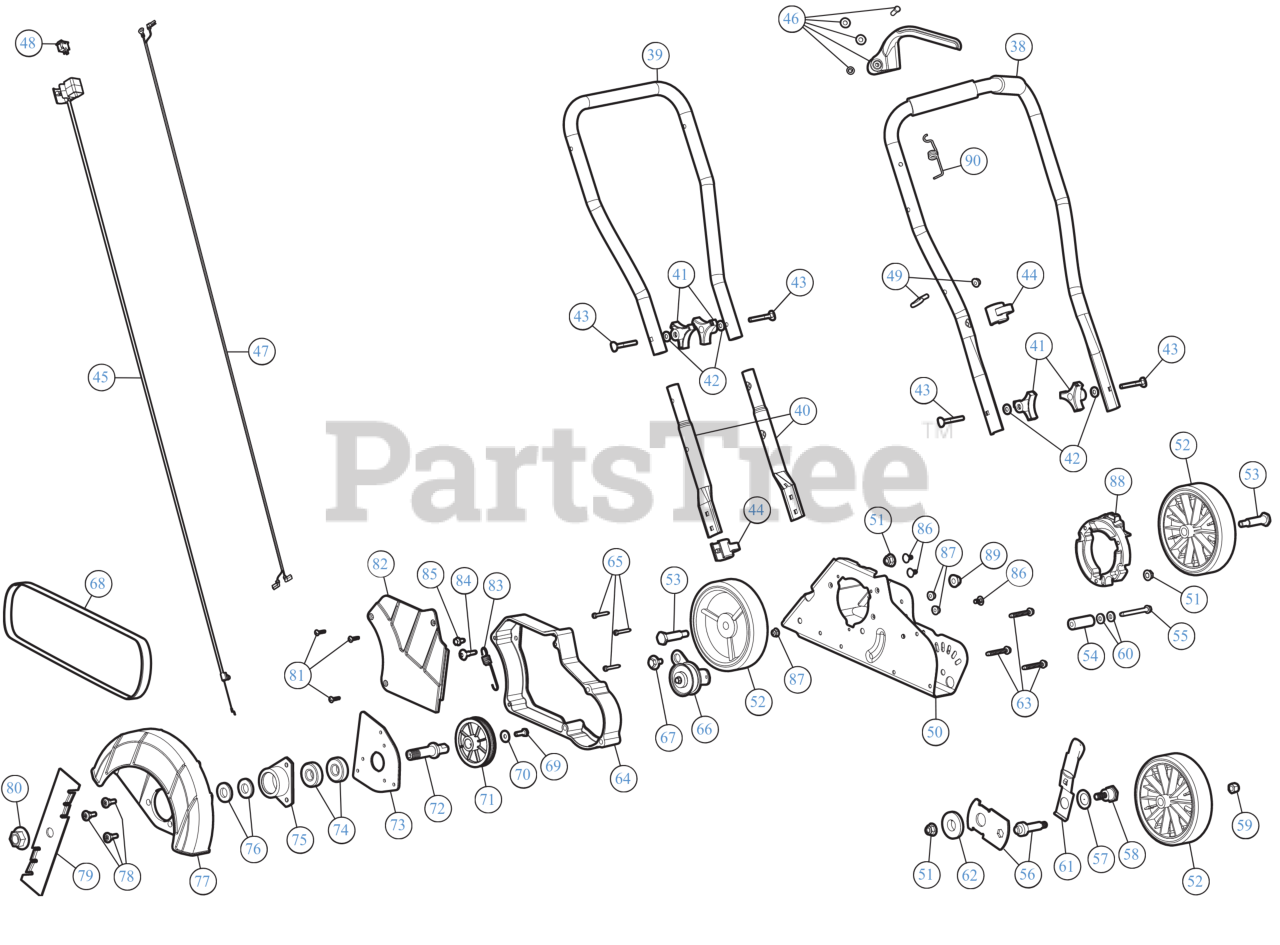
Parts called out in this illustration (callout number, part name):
38	HANDLE UP
39	HANDLE MID
40	HANDLE EXT
41	KNOB, 3-PRONG ¼ "-
42	WASH, FLAT SPECIAL
43	BOLT, CARRIAGE CRV
44	CABLE GUIDE
45	THROTTLE CABLE
46	THROTTLE LVR W/HDW
47	WIRE LEAD
48	SW, MOMENTARY ON/O
49	ROPE GUIDE
52	WHEEL 5-1.5 GRAY
53	SHOULDER SCREW
54	SPACER
55	SCREW 1/4-20 x 2.375
56	PIVOT ARM
57	BELL WASHER
58	SHOULDER SCREW .75 X.50 X3/8-16
59	HEX NUT INS L-3/8-16
60	SPACER
61	FRONT HEIGHT ADJUST LEVER ASSEMBLY
62	HEIGHT ADJUSTMENT BEARING
63	SCREW 1/4-20 x 1.750
64	SPACER
65	SCREW 8-16X1.25
66	IDLER PULLEY ASSEMBLY
67	SHOULDER SCREW .560X.165: 5/16-18
69	SCREW 1/4-20X.75 GR5
70	SPRING WASHER BELL
72	BLADE SPINDLE
73	SPINDLE MOUNT PLATE
74	BALL BEARING
75	BEARING CUP
76	FLAT WASHER .635 x 1.24 x .181
77	EDGER BLADE GUARD (W/LABEL)
78	SHOULDER SCREW .375X.280:1/4-14
79	EDGER BLADE
80	HEX NUT
81	SCREW 8-16 x 3/4
82	BELT COVER
83	SPRING
84	BOLT 1/4-20
85	SCREW 1/4-20 X.500
86	CARRIAGE BOLT 1/4-20X.50"
87	FLANGE LOCK NUT
88	SPACER
90	SPRING
